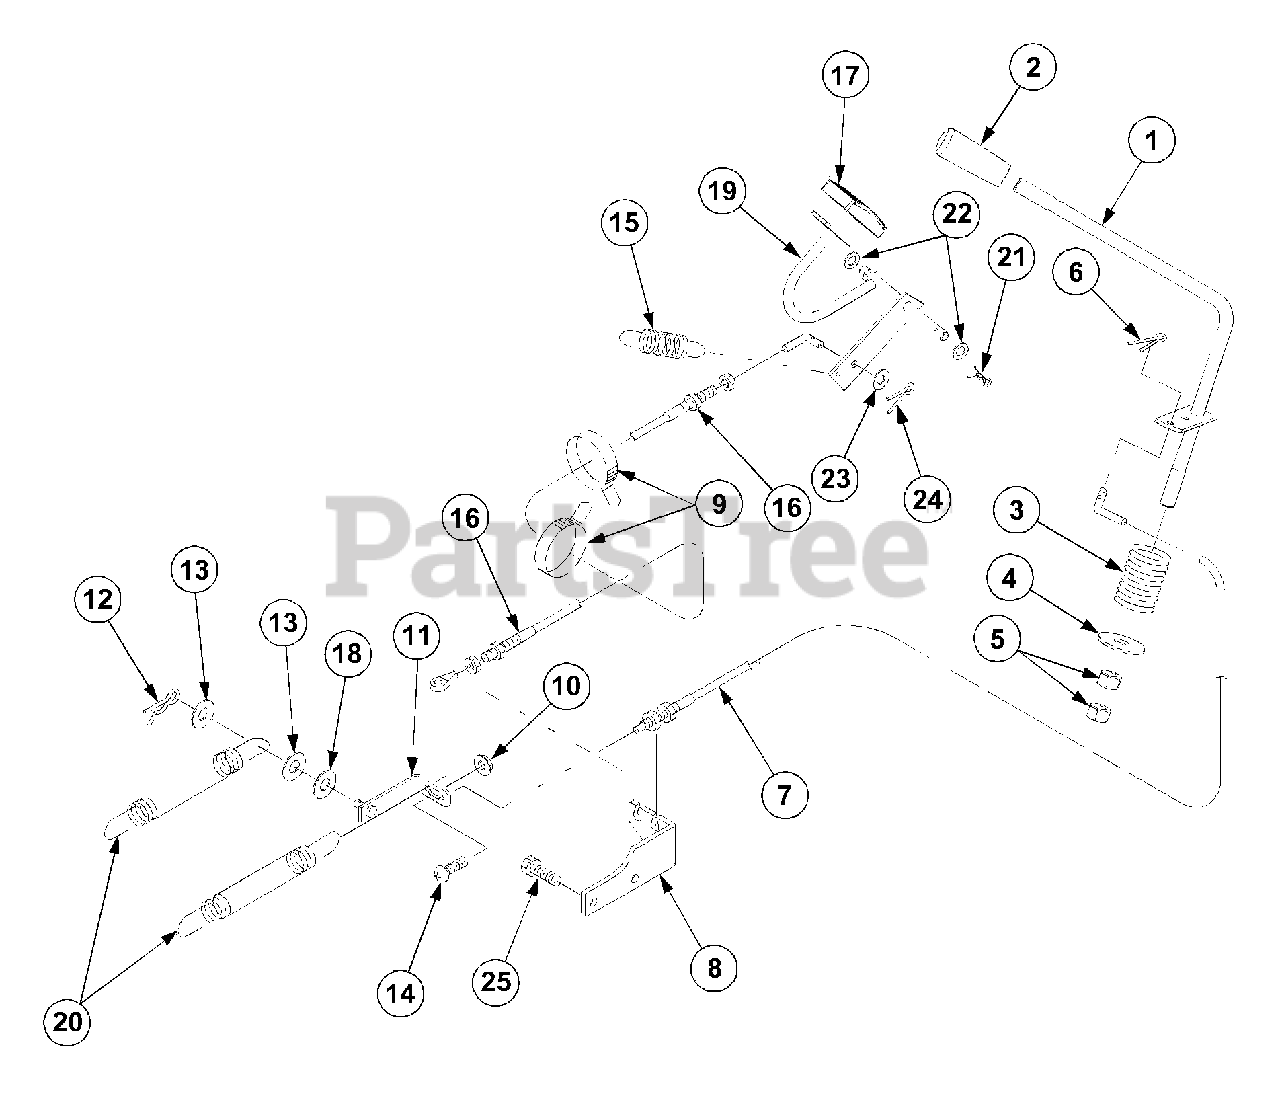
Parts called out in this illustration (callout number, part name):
1	Lever,Control
9	Band,Wire
14	Screw,w/Washer
15	Spring
16	Wire,Foot Accel
17	Cover,Pedal
19	Pedal,Accele
21	Pin,Snap
22	Washer
23	Washer
24	Pin,Split
25	Bolt,w/Washer
